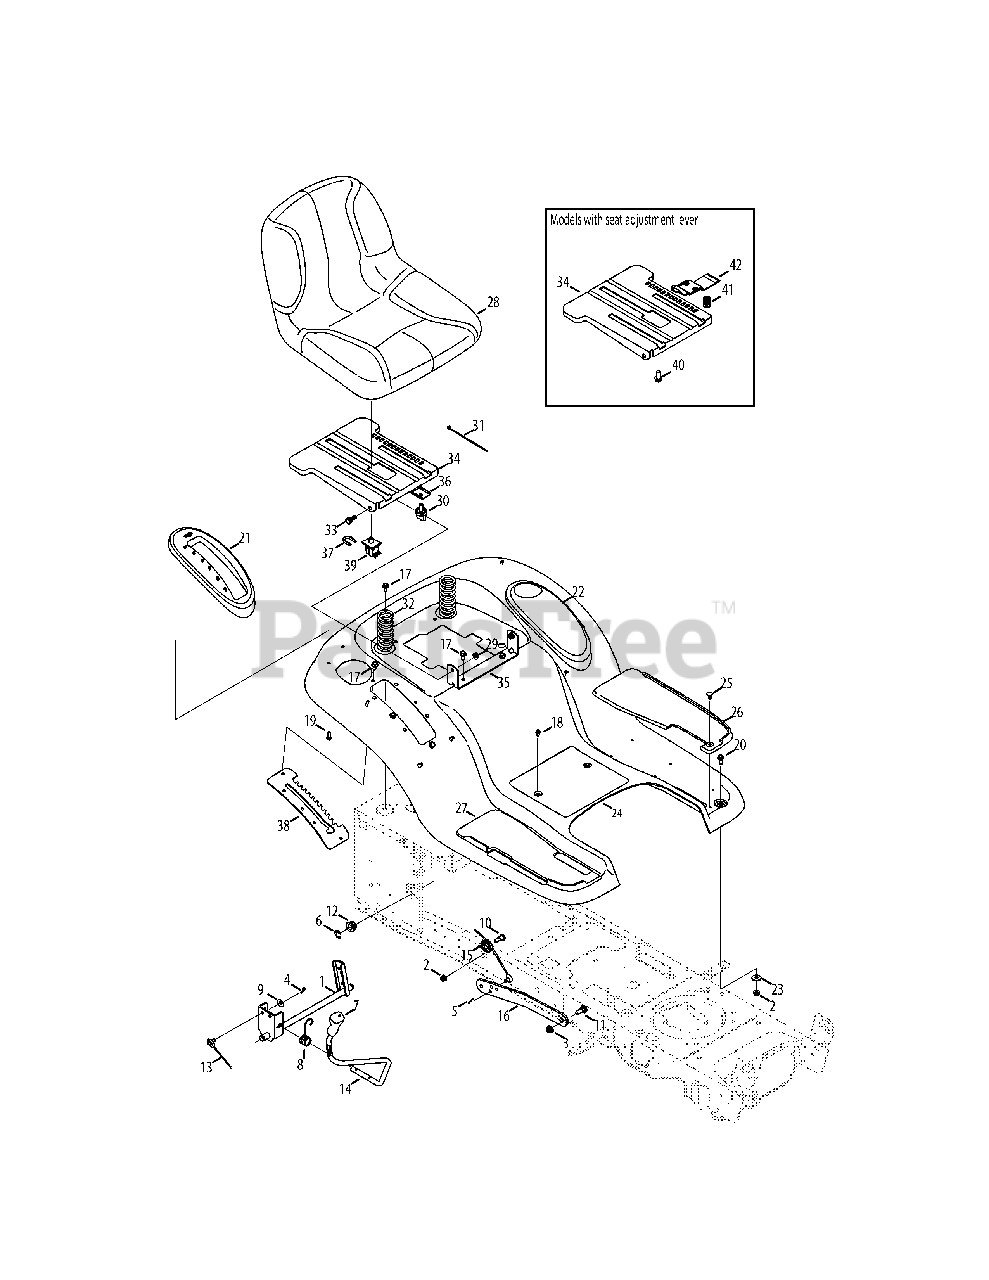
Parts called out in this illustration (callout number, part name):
1	Lift Shaft Assembly
2	Flangelock Nut, 5/16-18
3	Flangelock Nut, 3/8-16
4	Cotter Pin, .072 DIA. x 1.13 LG
5	Bow-Tie Cotter Pin
6	E-Ring, .625 DIA. SHAFT
7	Handle Grip
8	Torsion Spring
9	Spring Washer, .401 x .870 x .063
10	Shoulder Screw, .437 x .470:5/16-18
11	Shoulder Bolt, .500 x .270:3/8-16
12	Hex Flange Bearing
13	Lift Cable, 16.64 LG
14	Lift Handle
15	Pulley Roller Cable
17	Taptite Screw, Lock Washer, 5/16-18
18	Taptite Screw, Lock Washer, 1/4-20
19	Hi-Lo Screw, Lock Washer, 1/4-15
20	Taptite Screw, 5/16-18:.750
21	Lift Lever Cover
22	Cover with Cup Holder
23	Flat Washer, .344 x 1.00 x .063 HDN
25	Ratchet Clip
26	LH Foot Pad
27	RH Foot Pad
28	Seat
29	Flangelock Nut, 5/16-18
31	Cable Tie, 3/16 x .05 x 7.4
32	Compression Spring, 1.50 x 3.90 x .200
33	Shoulder Screw, .437 x .268:5/16-18
34	Seat Mounting Bracket
35	Seat Pivot Bracket
36	Knob Adjust Bracket
37	Switch Retainer Clip
38	Lift Bracket, 5 Style
39	Seat Switch
40	Hex Head Flange, 3/8-16:.875
41	Compression Spring, .68 x 1.065 x .055
42	Seat Adjustment Lever
